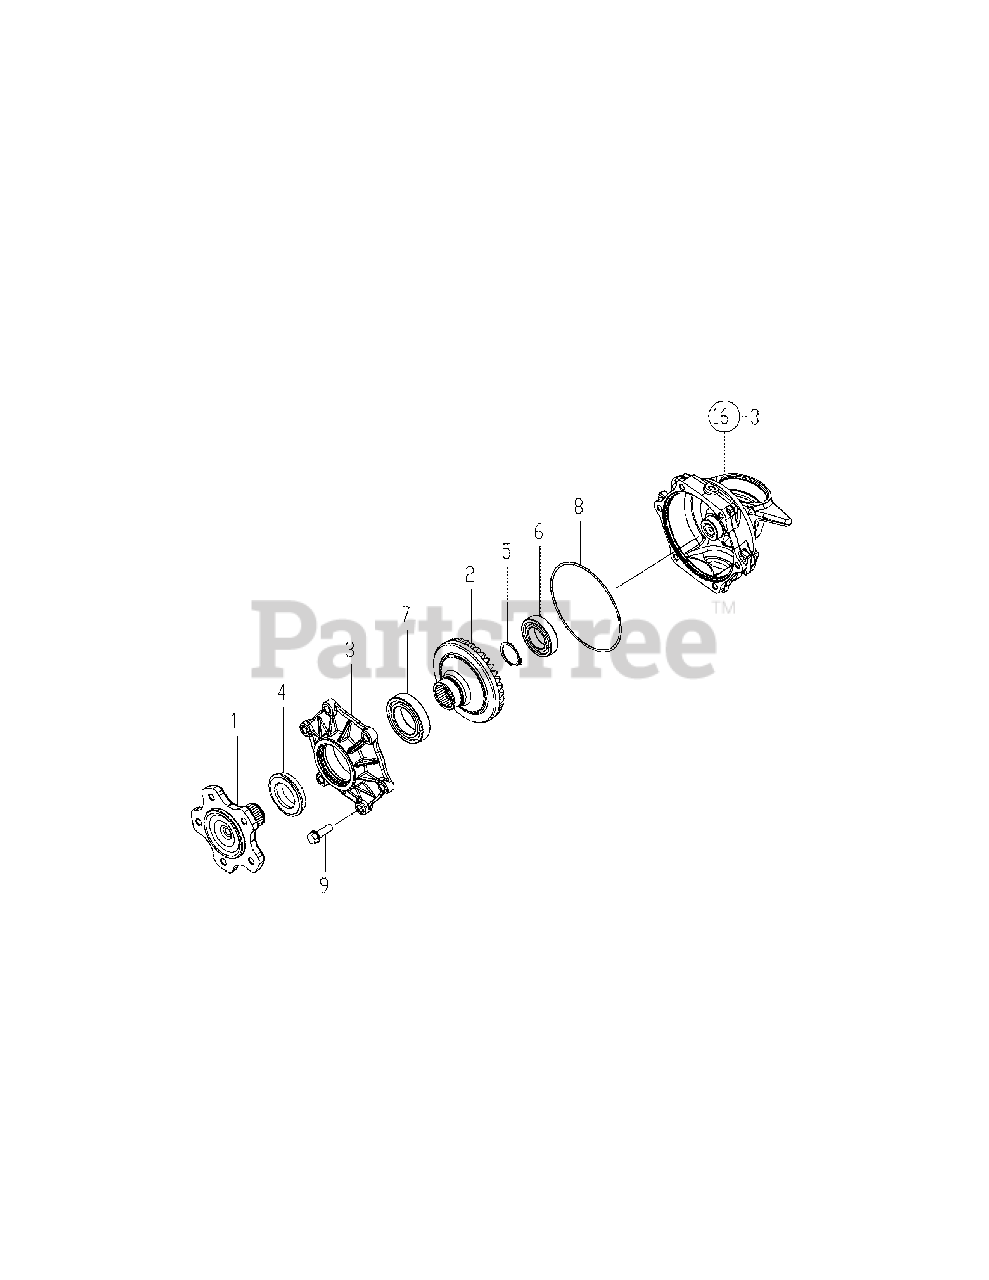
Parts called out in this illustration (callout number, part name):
1	Spindle, Front
3	Case, Front Bearing
4	Seal, Qlfy40X62X14
6	Bearing, 6007 Ntn
7	Bearing, 6009 Ntn
8	Packing, G130.0
